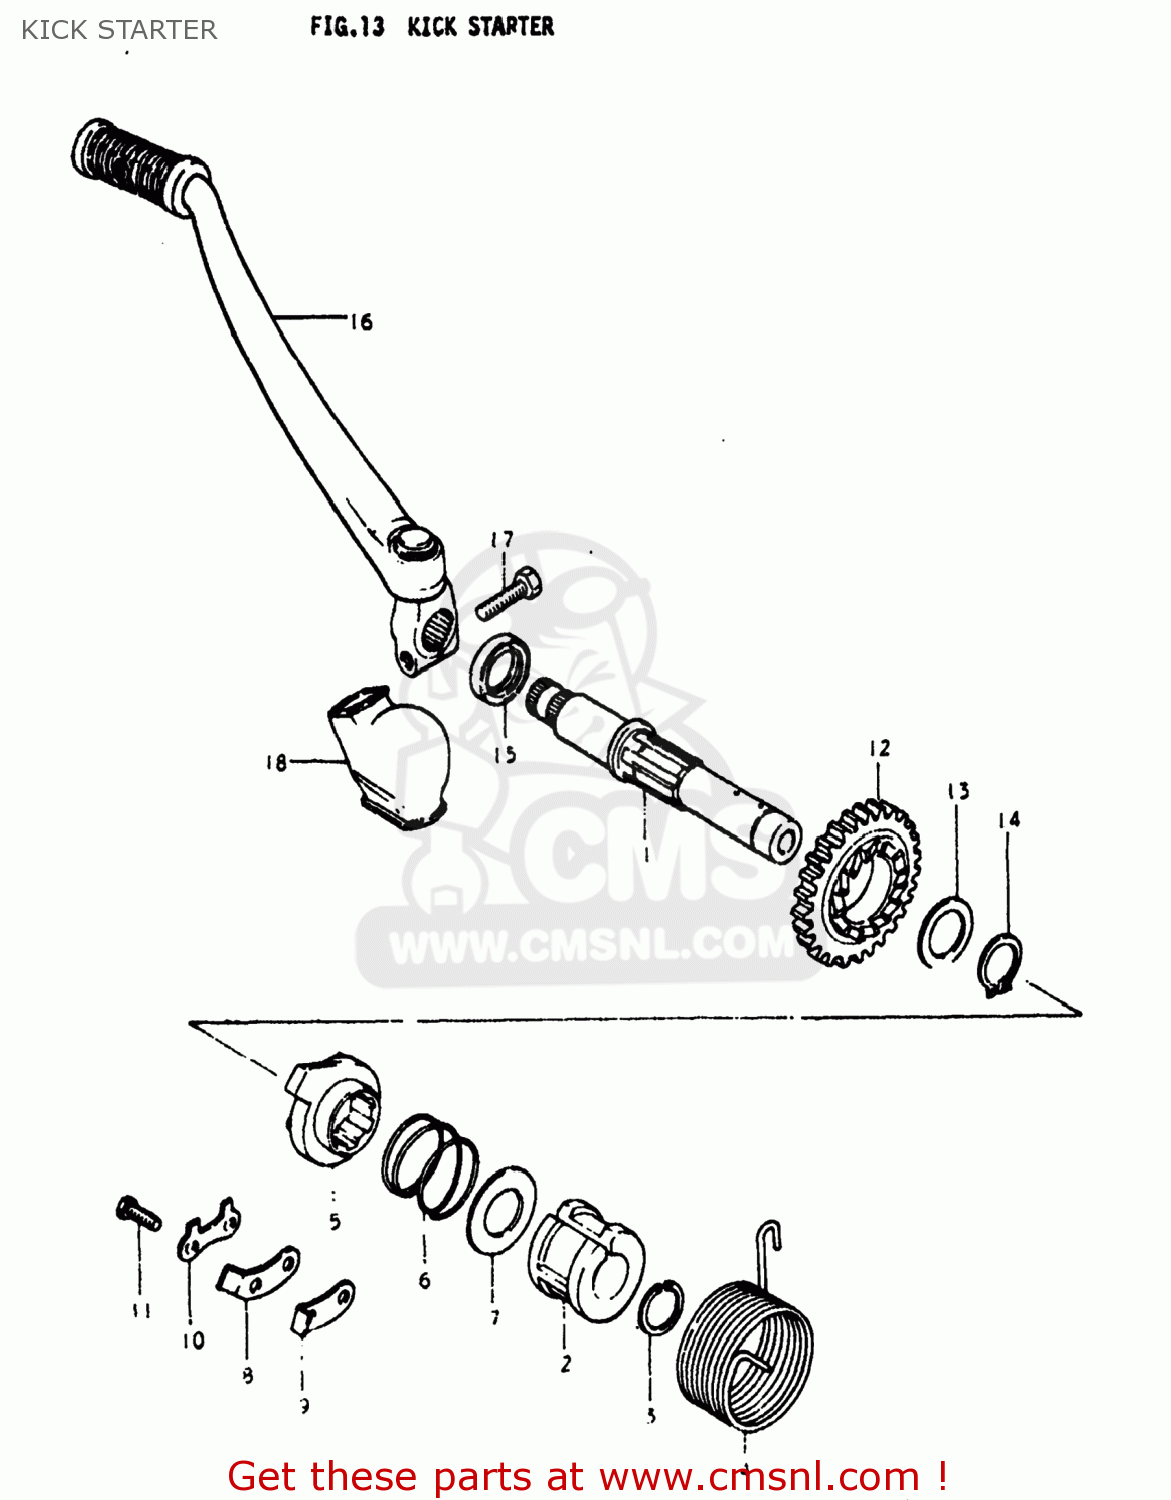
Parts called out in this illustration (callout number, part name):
1	SHAFT,KICK STARTER
2	GUIDE,KICK STARTER SFT SPRING
3	CIRCLIP
4	SPRING
5	STARTER,KICK
6	SPRING
7	WASHER
8	GUIDE,KICK STARTER
9	STOPPER,KICK STARTER
10	WASHER
11	BOLT, UPPER
12	GEAR,KICK STARTER DRIVE
13	SHIM
14	CIRCLIP
15	SEAL,OIL(20X27X5)
16	LEVER ASSEMBLY,KICK STARTER
17	BOLT(8X25)
18	COVER,KICK LEVER JOINT
